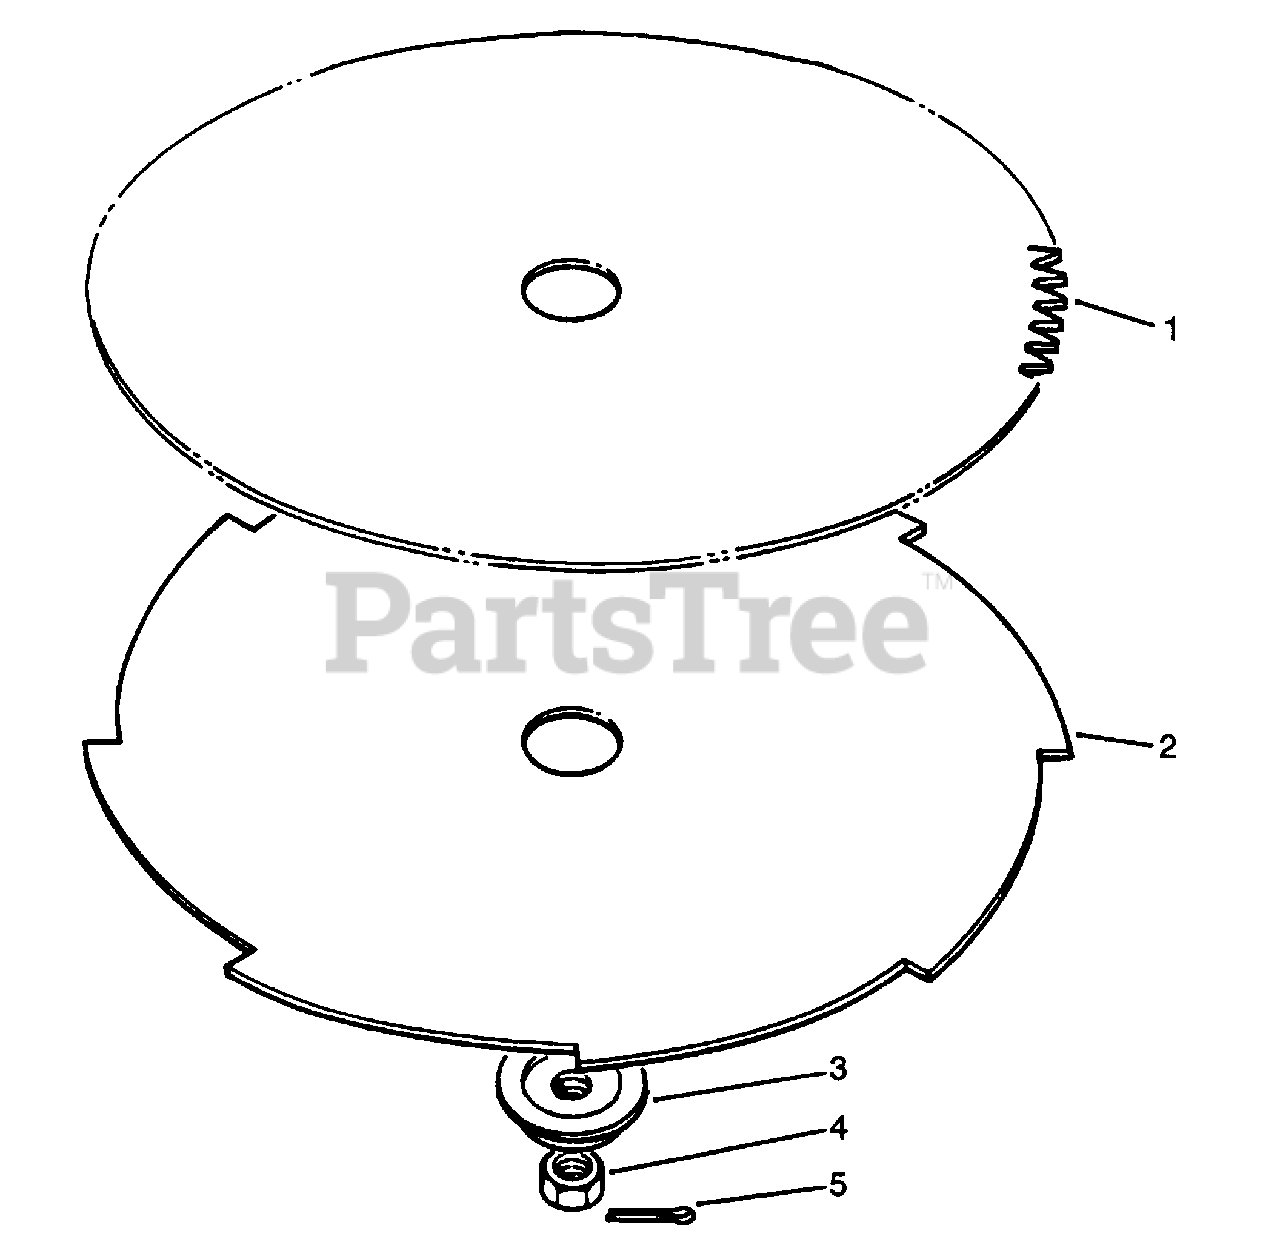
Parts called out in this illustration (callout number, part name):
1	8" Dia. Saw Blade (80 Tooth)
2	8" Dia. Brush Blade (8 Tooth)
3	Adaptor-Blade
4	Nut L.H.
5	Pin Cotter
